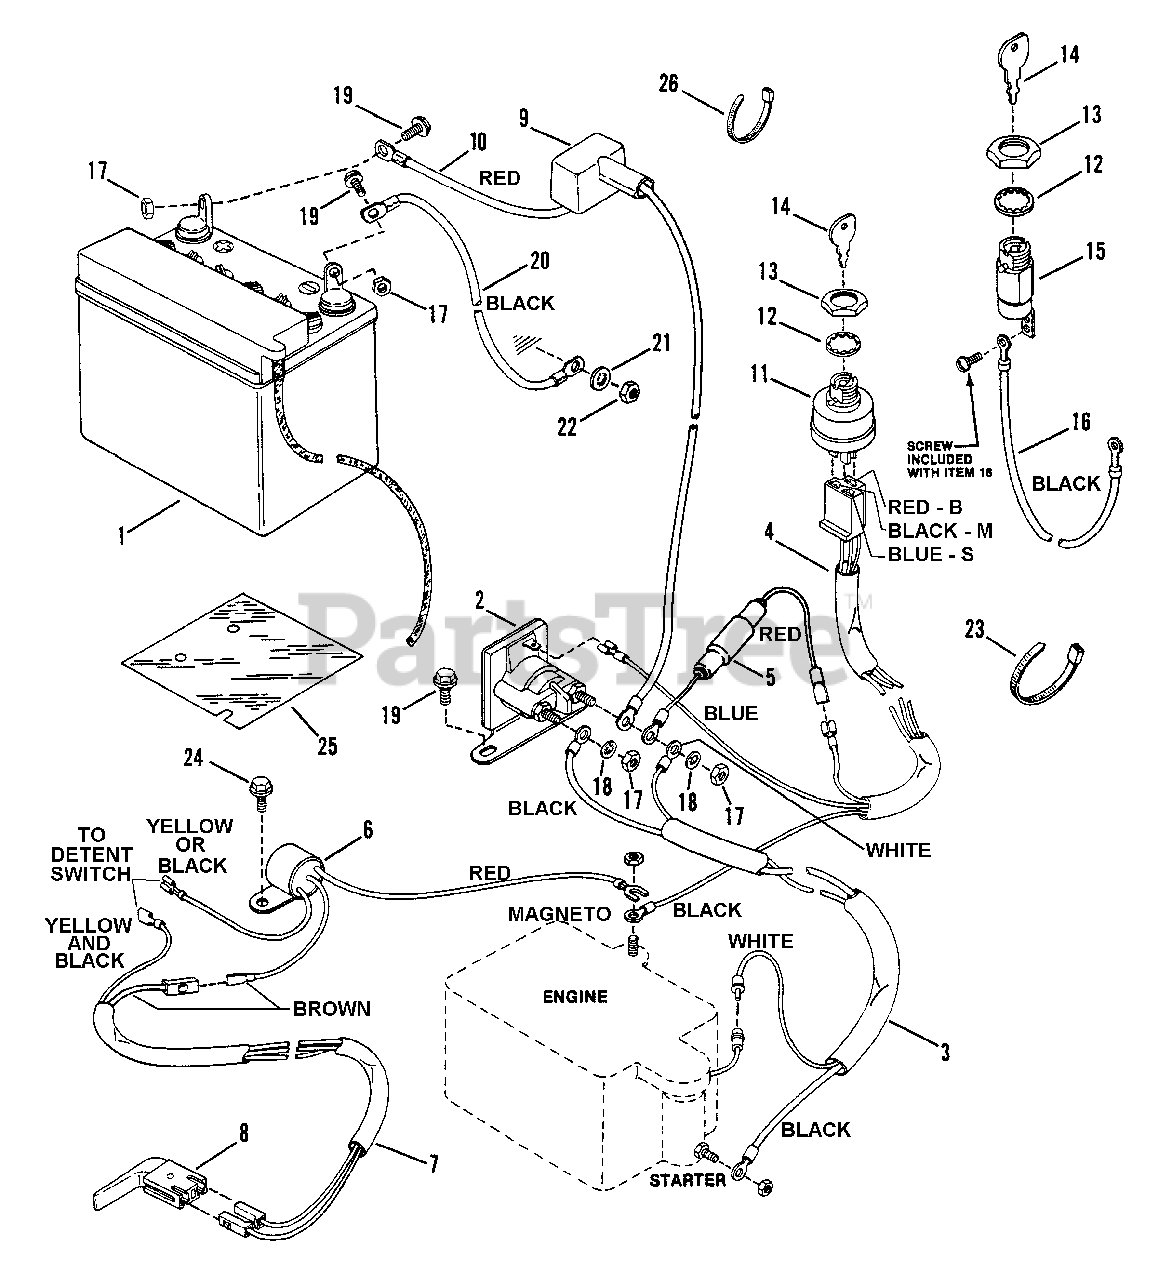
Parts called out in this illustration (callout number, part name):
1	KIT, 12V Dry Charge Battery
2	SOLENOID
3	HARNESS, Starter Wiring
4	HARNESS, Ignition Wiring
5	HOLDER, Fuse
6	INTERLOCK
7	HARNESS, Deck Interlock Wiring
8	SWITCH, Deck Interlock
9	COVER, Battery Cable
10	CABLE, Positive (Red)
11	SWITCH, Ignition
12	WASHER, 5/8 Internal Tooth Lock
13	NUT, 5/8-32 Hex
14	KEY, Switch (With Cover)
15	SWITCH, Ignition
16	WIRE, Ground
17	NUT, 1/4-20 Hex Center Lock
18	WASHER, 1/4 Internal Tooth Lock
19	SCREW, 1/4-20 x 5/8" Hex Head Cap
20	CABLE, Negative
21	WASHER, 5/16 Internal Tooth Lock
22	NUT, 5/16-18 Hex
23	TIE, 7" Long Cable
24	SCREW, 1/4-20 x 1/2" Self-Tapping
25	PROTECTOR, Solenoid
26	TIE, 2" Long Cable
